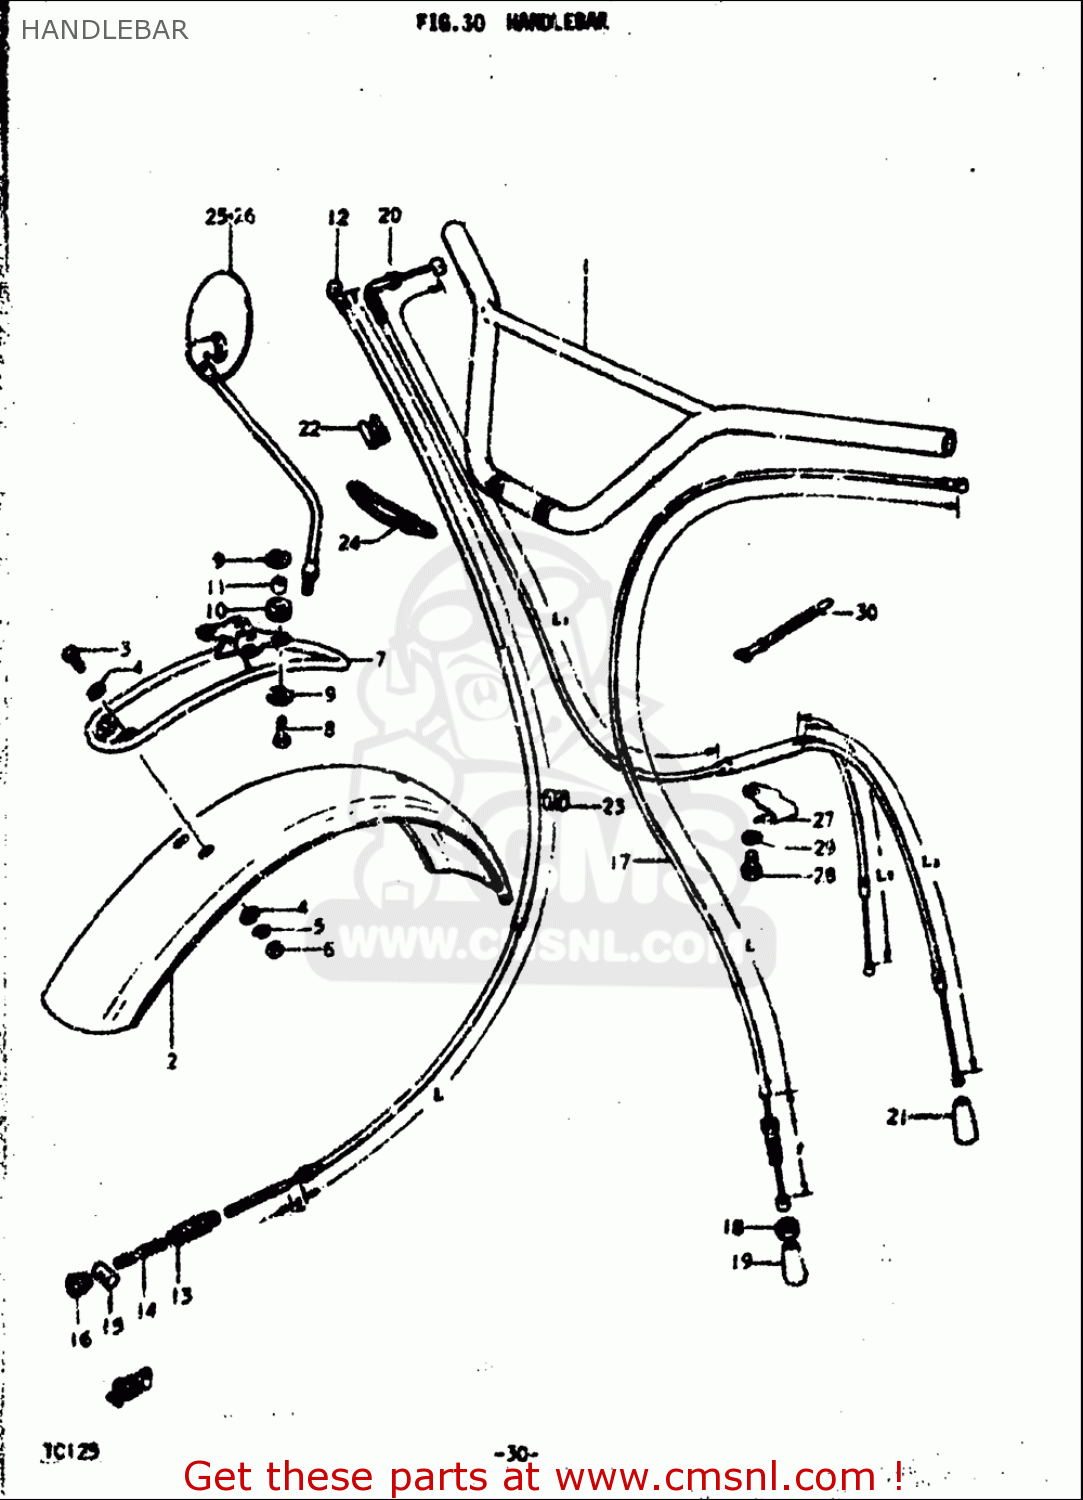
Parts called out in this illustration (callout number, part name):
3	BOLT(6X14)
4	WASHER
5	WASHER,LOCK
6	NUT
8	BOLT
9	WASHER(6.5X20X1.2)
10	CUSHION
11	SPACER(6.1X9X7.5)
12	CABLE,FR BRAKE
13	SEAL,DUST(7X16X75)
14	SPRING
15	BRAKE ROD LEVER
16	BRAKE ROD ADJ N
17	CABLE ASSY,CLUTCH
18	NUT
19	SEAL,DUST(7X18X30)
20	CABLE ASSY,THROTTLE
21	SEAL,DUST(7X18X30)
22	CLAMP
23	CLIP
25	MIRROR ASSY,RR VIEW,R
26	MIRROR ASSEMBLY,LEFT
28	BOLT
29	WASHER,LOCK
30	CLAMP(L:120)
